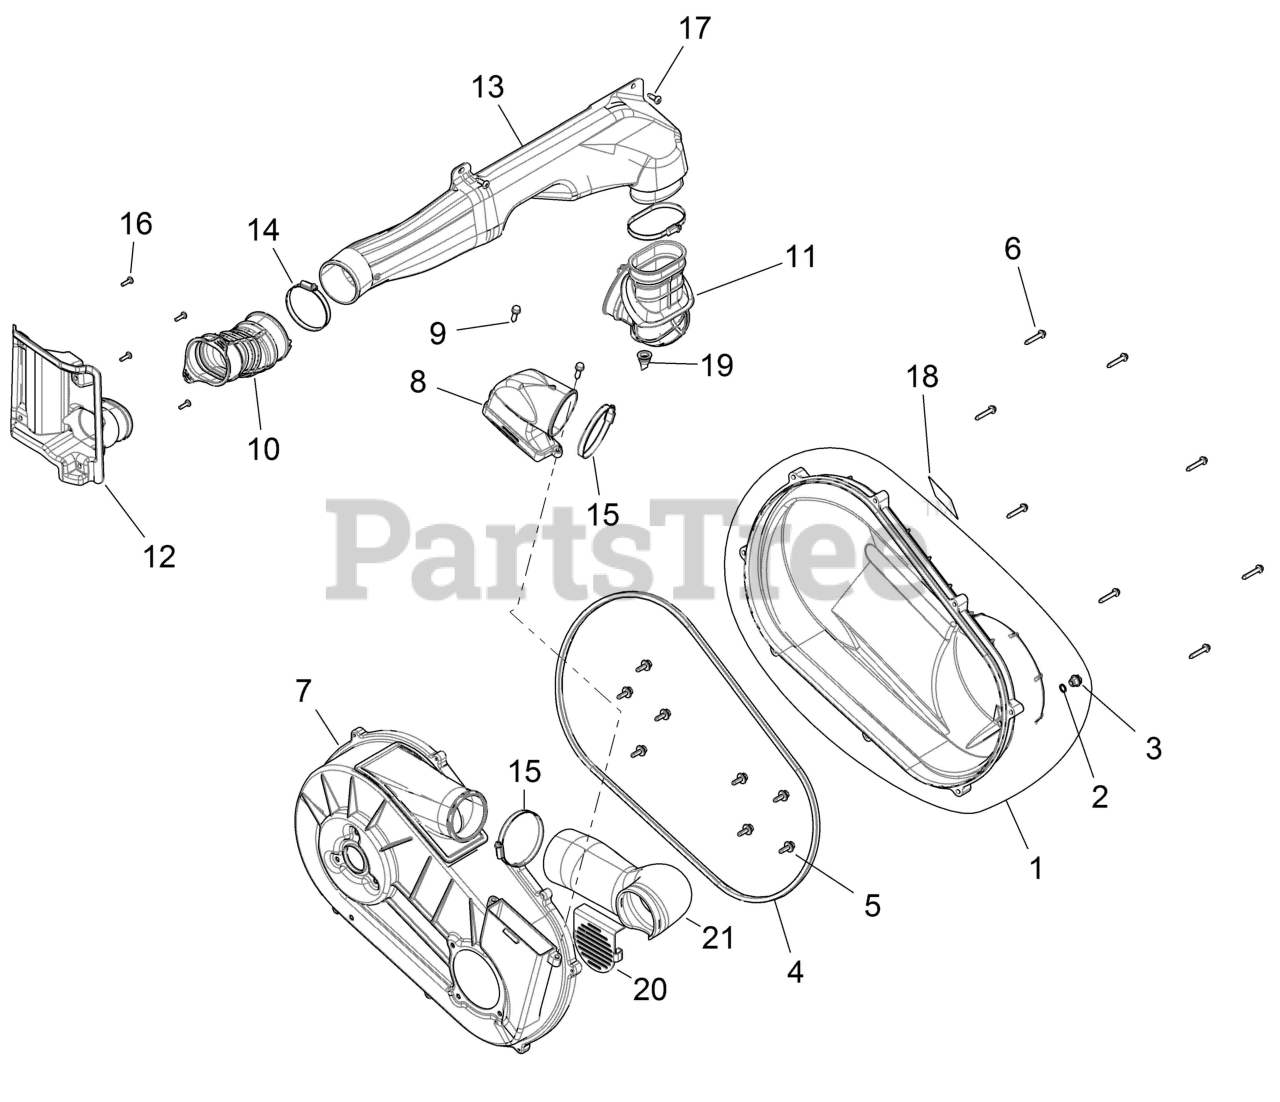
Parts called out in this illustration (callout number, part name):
1	ASM-COVER,CLUTCH,OUTER
2	O RING-.364X.504X.07
3	PLUG-DRAIN
4	SEAL-OUTER CLUTCH COVER
5	ASM-BOLT/WASHER,20 MM
6	SCR-HXFL-M6X35 ZOD HILO
7	ASM, INNER CLUTCH COVER
8	DUCT-CLUTCH,AIR IN
9	SCREW (10)
10	HOSE-INTAKE,CLUTCH
11	HOSE-CLUTCH,AIR IN,TRAP,570
12	INTAKE-FENDER-REAR
13	DUCT-INTAKE,CLUTCH
14	CLAMP,BAND,NARROW (10)
15	CLAMP-BAND,NARROW 70-90MM
16	SCR-10X5/8-HI/LO,PN-T25,TRX-M
17	SCR-TX TRUSS-#14X3/4,HI/LO ZBK
18	DECAL, BELT, CAUTION/CHECK
19	PLUG-DRAIN
20	BRKT, GRATE
21	HOSE, CLUTCH OUTLET
